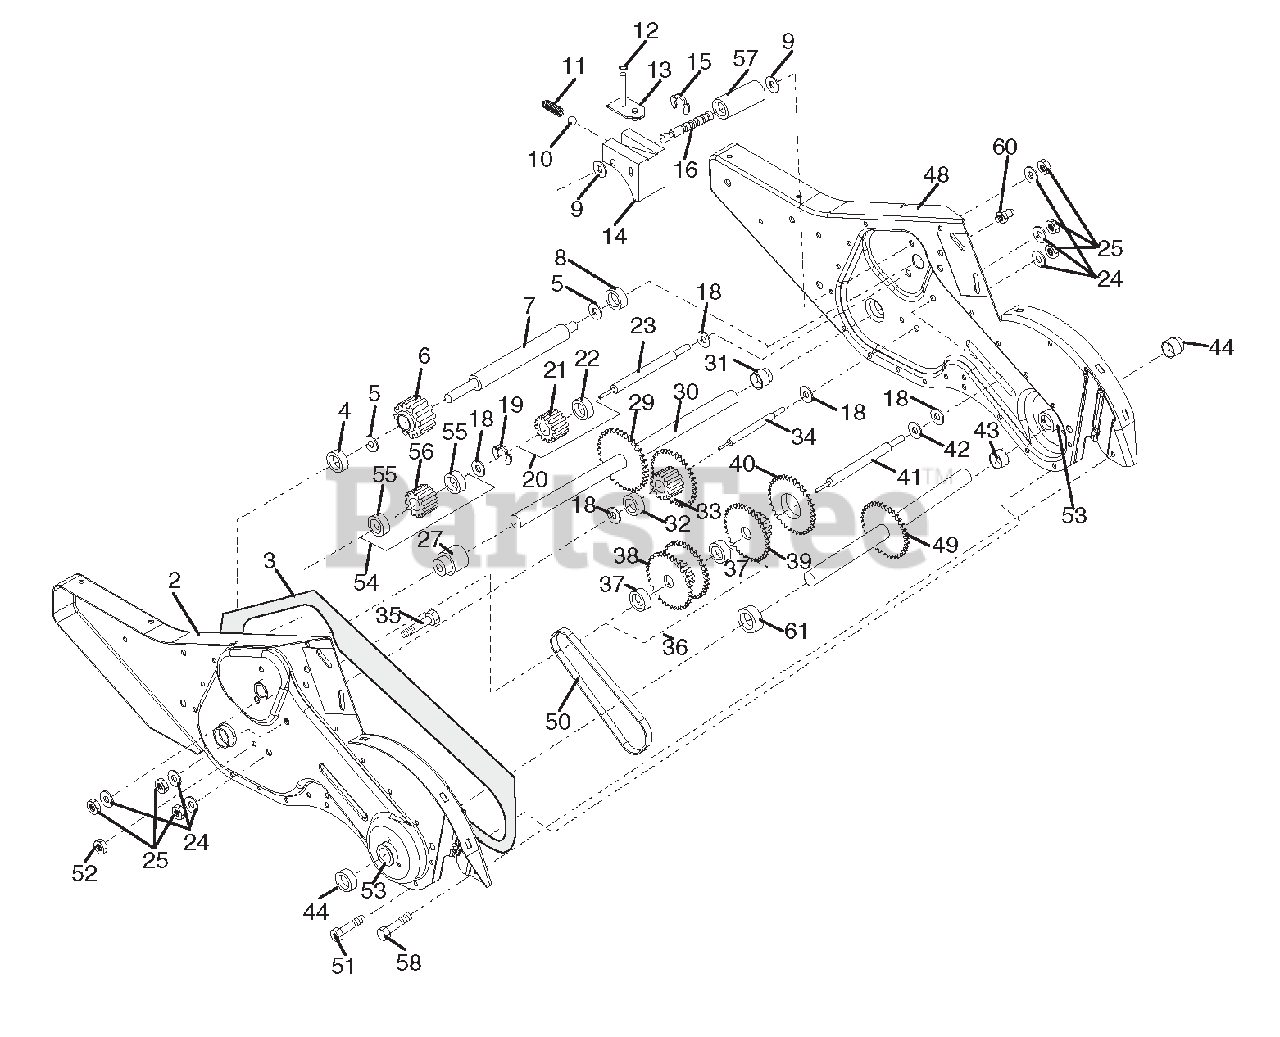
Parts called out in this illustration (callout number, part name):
1	Transmission Assembly (Include
2	Gearcase, LH w/Bearing (Includ
3	GASKET, GEARGASE
4	Bearing, Needle
5	Washer, Thrust 5/8 x 1.10 x 1/
6	Pinion, Input
7	Shaft, Input
8	BEARING, NEEDLE
9	Washer, Seal
10	BALL, STEEL
11	Spring, Shift, Fork
13	Arm, Shift
14	Fork, Shift
15	Ring, Klip
16	Shaft, Shift
19	Ring, Klip
20	Gear, Assembly, Reverse Idler
21	Gear, Reverse Idler
22	Bearing, Needle
23	Shaft, Reverse Idler
24	WASHER.LOCK.HVY HLCL.SPR.7/16
25	Nut, Hex 7/16-20
27	BEARING, SHAFT, GROUND DRV LH
29	Chain #35-50 Pitch
30	Ground Shaft Assembly
31	Bearing, Shaft, Ground Drive R
32	Spacer 0.70 x 1.00 x 1.150
33	Sprocket and Gear Assembly
34	Shaft, Reduction (2nd)
35	Screw, Whiz, Lock 5/16-18 x 3-
36	Sprocket Assembly w/Bearing (I
37	Bearing, Needle
38	Sprocket, Tine
39	Gear, Cluster, Red 1st & 2nd
40	Gear, Reverse
41	Shaft, Reduction (1st)
42	Washer, Thrust
43	Spacer 1.01 x 1.75 x 0.760
44	Seal Asm. Oil
48	Gearcase, RH w/Bearing (Includ
49	SHAFT, TINE
50	Chain, Roller #50-50 Pitch
51	Screw 1/4-20 x 1/2
52	Nut, Hex 5/16-18
53	Bearing Kit, Tine Shaft
54	Gear, DRT Idler w/Bearing (Inc
55	Bearing, Needle
56	Gear, DRT Idler
57	Spacer, Split .52 x .64 x 1.04
58	Screw 1/4-20 x .875
60	Fitting Grease
61	SPACER 1.015 X 1.50 X .650
